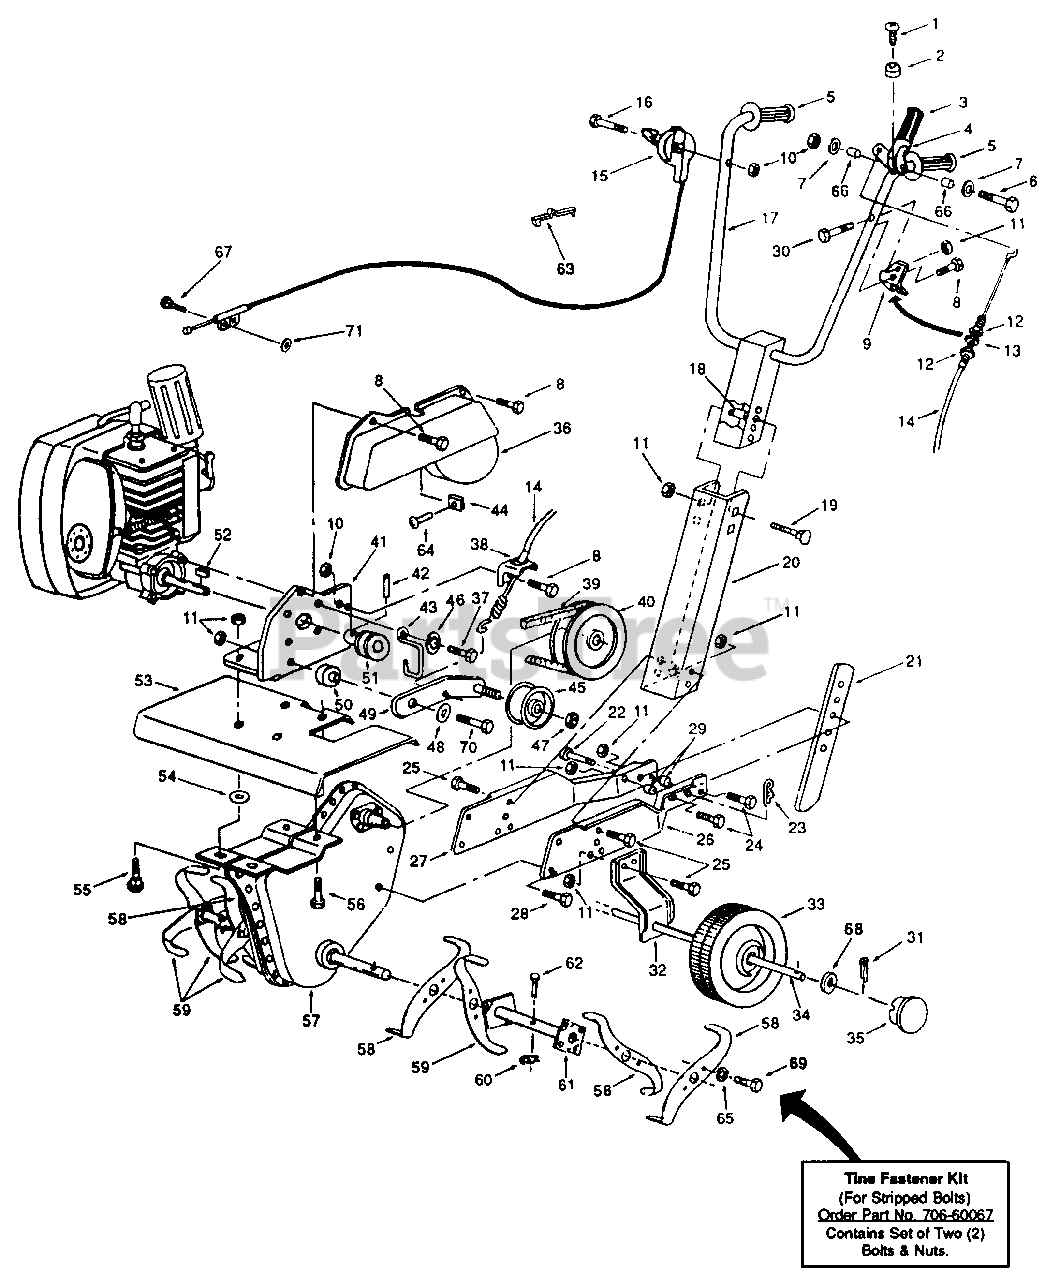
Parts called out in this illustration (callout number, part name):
1	SCREW-TAP 10X16X.50
2	BUMPER-RECESS
3	VINYL-PLASTIC
5	GRIP-LIFT HANDLE
6	SCREW-HEX 1/4-20 X 2.00
7	WASHER-FL
8	SCREW-SLOT PL-250-20X0.50
9	BRACKET-CLUTCH
10	NUT-INS LOCK 1/4-20
11	NUT-HEX INS L-5/16-18
12	NUT-HEX JAM 5/16-24
13	WASHER-LOCK-5/16
14	CABLE-CLUTCH
15	CONTROL-THROTTLE (TILLER)
16	SCREW-HEX 1/4-20 X 1.50
19	BOLT-CARRIAGE 5/16-18 X 2.50
22	PIN-CLEVIS
23	PIN-INTERN COT
24	SCREW-HEX 5/16-18 X 1.00
25	SCREW-HEX 5/16-18 X .62
26	FRAME HALF-RH
27	FRAME HALF-LH
28	SCREW-TAP 5/16-18X.62
29	SPACER-.34 X .50 X .31
30	SCREW-HEX-.312-18X1.250
31	PIN-COTTER-3/32 DIA X 1.00
32	BRACKET-WHEEL
34	AXLE-WHEEL (MINI TILLER)
36	COVER-BELT SEARS
37	SCREW-HEX 1/4-20 C .62
38	BRACKET-CLUTCH LEVER
41	PLATE-ENGINE MTG
42	SCREW-SET 5/16-18 X 3/8 LG
43	RETAINER-BELT
44	CLIP-TINNERMAN
45	PULLEY-IDLER-FLAT W/FLANGES
46	WASHER-INTERN L 1/4
47	NUT-HEX INS L-3/8-24
48	WASHER-FL (#46041)
49	ARM ASSY-IDLER (TILLER)
50	SPACER-IDLER ARM
51	PULLEY-ENGINE
52	KEY-SQ .125 X .750
53	SHIELD-TINE (RED)
55	BOLT-CARRIAGE 5/16-18 X 1.00
56	SCREW-HEX 5/16-18 X .75
57	CASE ASSY-CHAIN COMP
58	TINE-10IN-RH
59	TINE-LH-10IN
60	PIN-COTTER
61	ADAPTOR ASSY-TINE
62	PIN-CLEVIS
63	TIE-PLASTIC
64	SCREW-PH-RD-#10-16 X .750
65	LOCK WASHER 1/4 DIA
66	SPACER-SPLIT
67	SCREW-PH 8-32X1.000
68	WASHER-FL-.406 ID X .74 OD X .063
69	SCREW-HEX WASH SF TAPP
70	SCREW-HEX 5/16-18 X 1.50
71	WASHER-FL-.20 X .395
